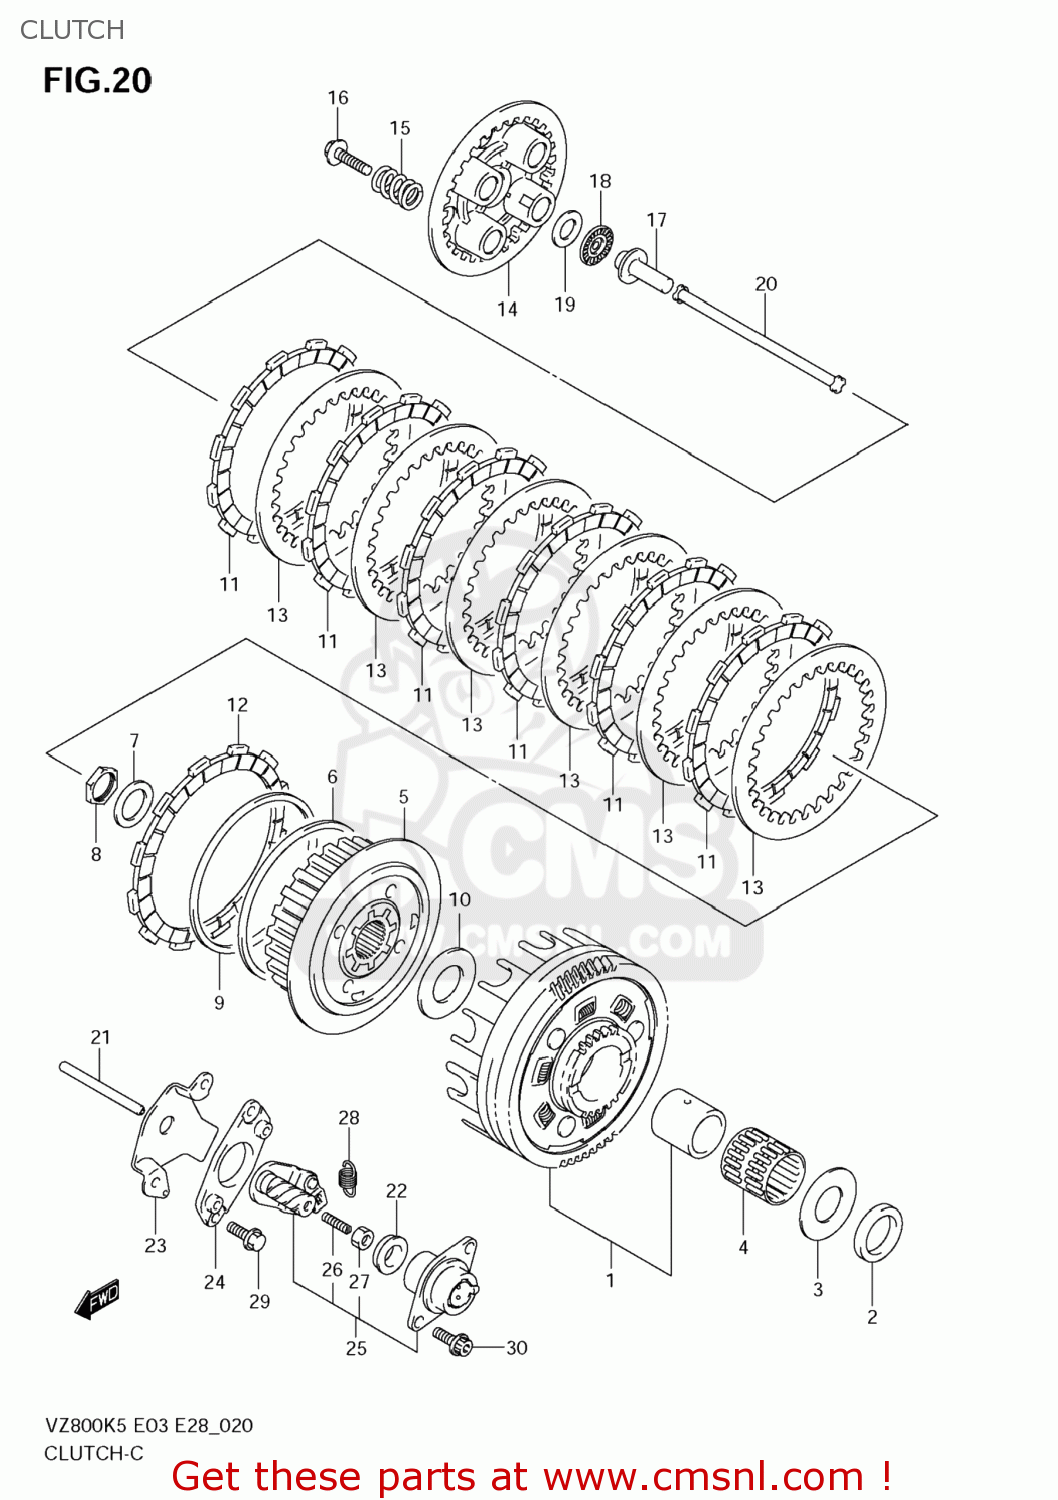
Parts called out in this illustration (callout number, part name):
1	GEAR ASSY,PRIMARY(NT:71)
2	SPACER(25X38X6.5)
3	WASHER(25X50X2.5)
4	BEARING(35X40X35.8)
5	HUB,CLUTCH SLEEVE
6	SEAT,WAVE WASHER(T:1.4)
7	WASHER
8	NUT
9	WASHER
10	WASHER(25X50X2.5)
11	PLATE,CLUTCH DRIVE (NAS)
12	PLATE,CLUTCH DRIVE(T:3.5) (NAS)
13	PLATE,CLUTCH DRIVEN(T:1.6) (NAS)
14	DISC,CLUTCH PRESSURE
15	SPRING,CLUTCH
16	BOLT(6X30)
17	PIECE,CLUTCH PUSH
18	BEARING(15X28X2)
19	WASHER(15.5X28X1)
20	ROD,CLUTCH
21	ROD,CLUTCH PUSH,L
22	SEAL,OIL(6X34X11)
23	RETAINER,CL PUSH ROD OIL SEAL
24	PLATE,CLUTCH RELEASE SCREW
25	SCREW ASSY,CLUTCH RELEASE
26	SCREW(6X25)
27	NUT
28	SPRING
29	BOLT
30	BOLT
